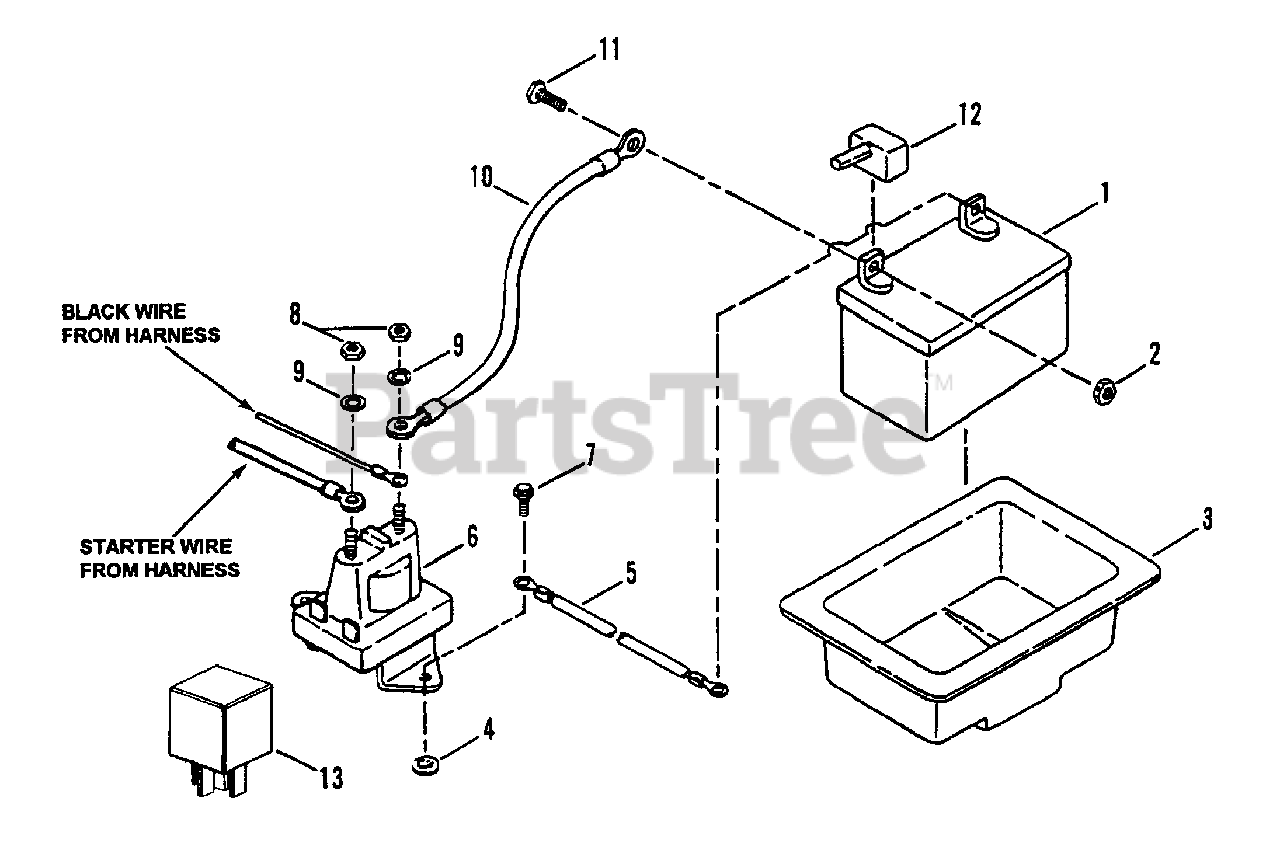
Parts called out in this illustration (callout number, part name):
1	KIT, Battery
2	NUT, 1/4-20 Hex Center Lock, Grade 5 or B
3	TRAY, Battery
4	RETAINER, Screw
5	CABLE, Ground (Black)
6	SOLENOID
7	SCREW, 1/4-20 x 1/2" Self-Tapping
8	NUT, 1/4-20 Hex Jam
9	WASHER, 1/4 Internal Tooth Lock
10	CABLE, Positive (Red)
11	SCREW, 1/4-20 x 5/8" Hex Head Cap, Grade 5
12	COVER, Positive Terminal
13	RELAY
